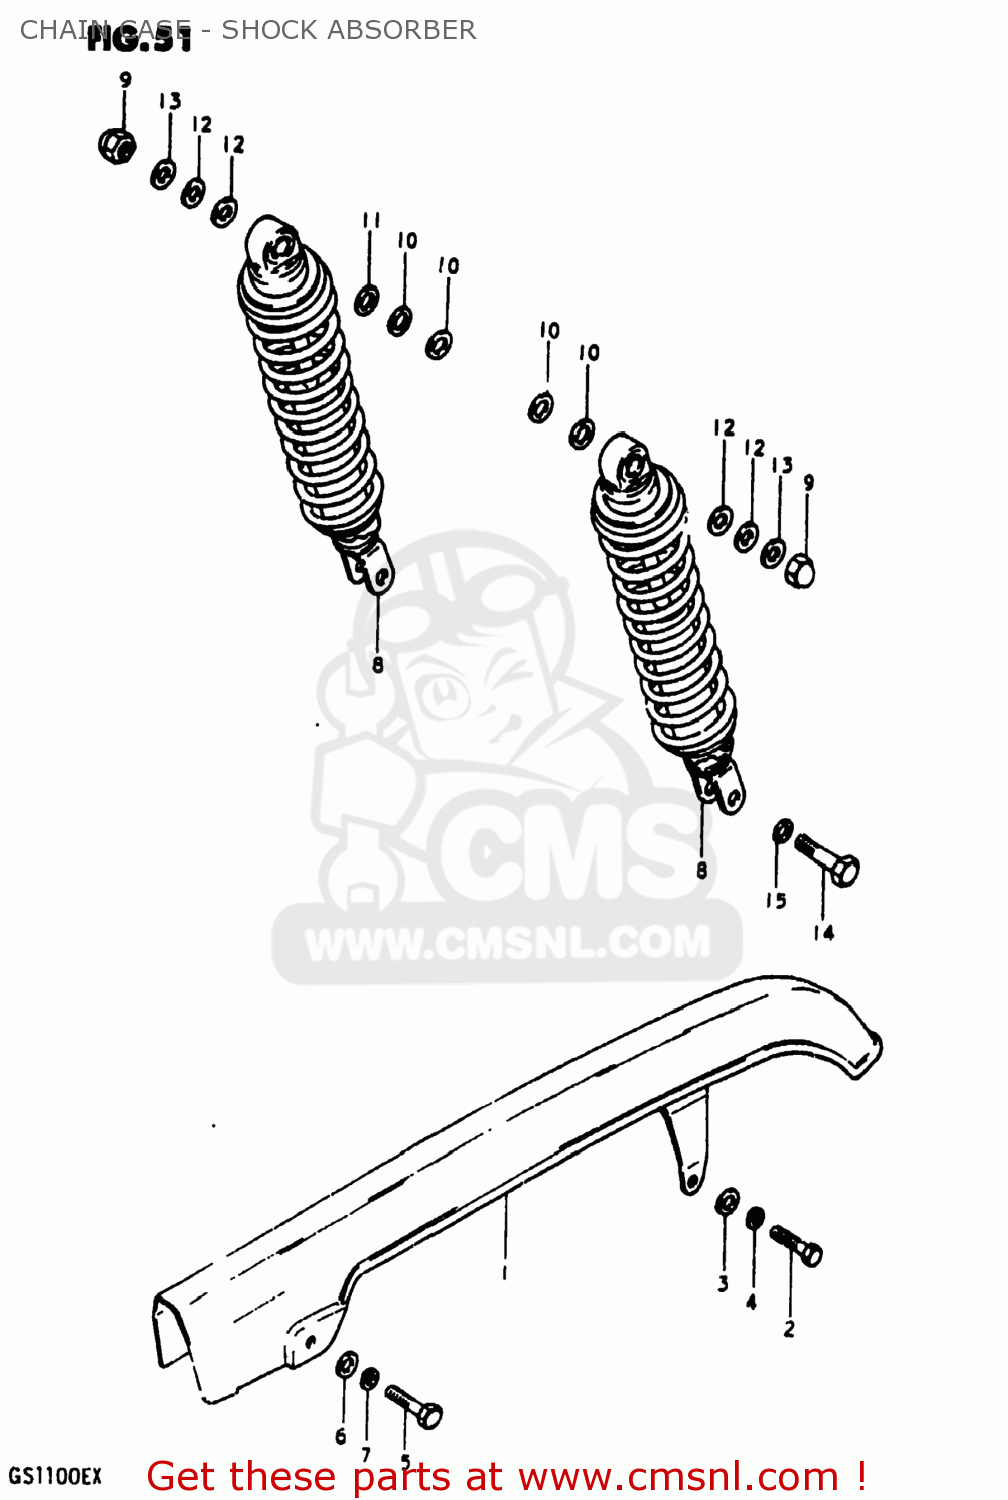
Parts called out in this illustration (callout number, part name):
1	CHAIN CASE
2	BOLT
3	WASHER
4	LOCK WASHER
5	BOLT
6	WASHER
7	LOCK WASHER
8	SHOCK ABSORBER, REAR
9	NUT, LOWER LH
10	WASHER
11	WASHER (12.5X24X3.2)
12	WASHER
13	WASHER(10.5X24X3.2)
14	BOLT(10X36)
15	WASHER
